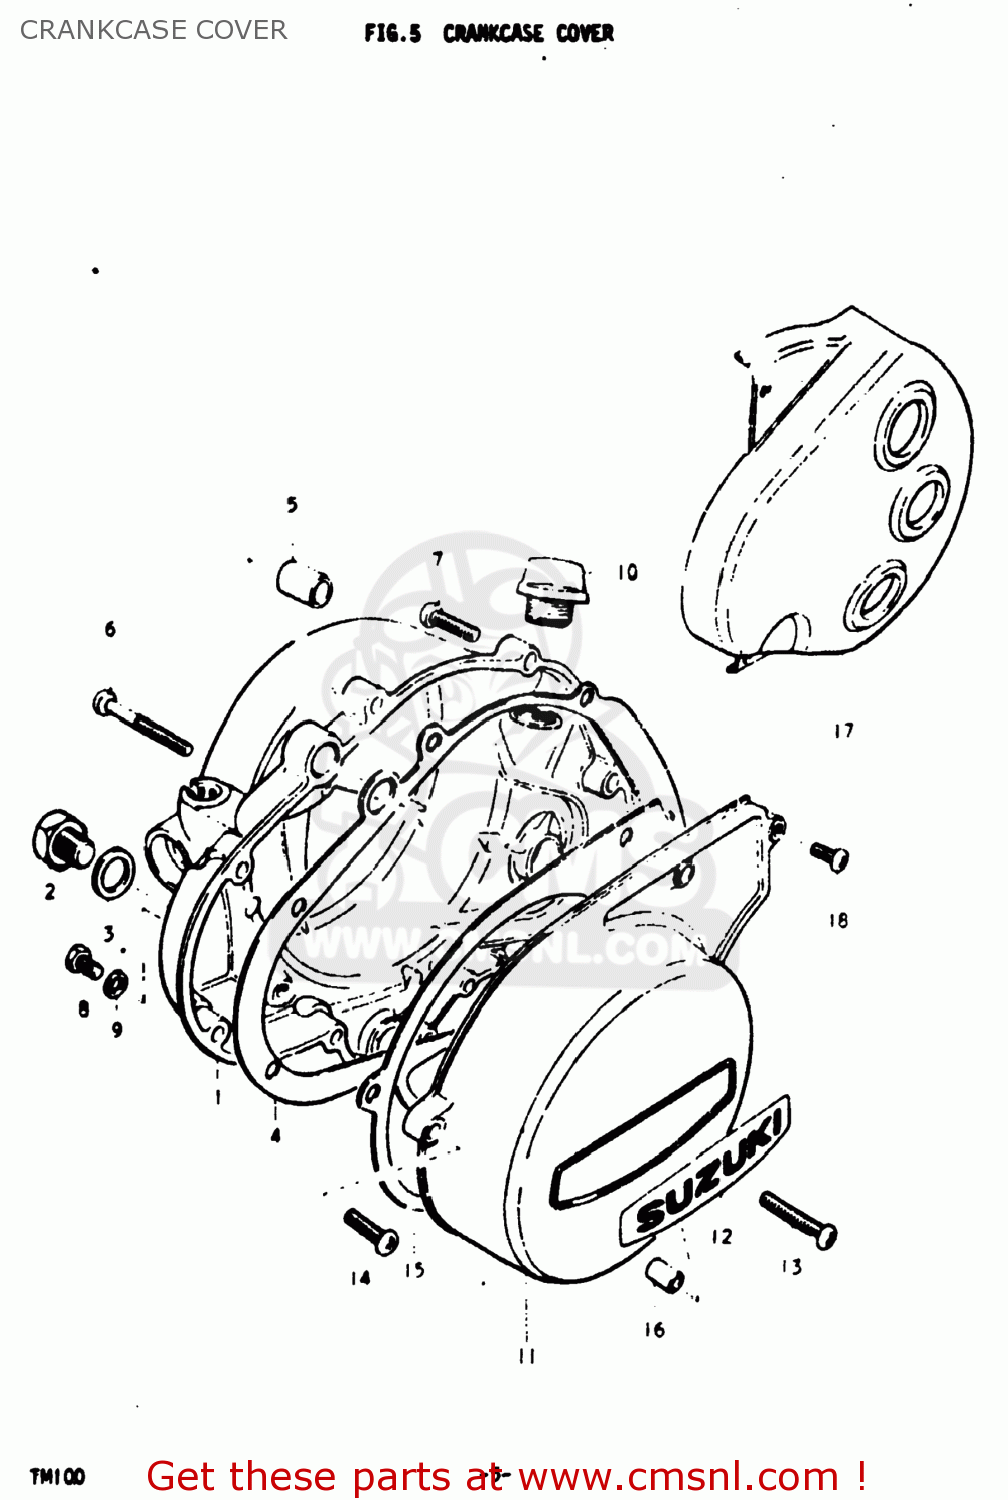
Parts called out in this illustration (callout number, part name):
1	CLUTCH COVER
2	PLUG
3	GASKET(14X19.2X2) (NAS)
4	GASKET,CLUTCH COVER (MCA)
5	PIN
6	SCREW (6X45)
7	SCREW
8	SCREW(6X10)
9	GASKET(6.2X11X1) (NAS)
10	PLUG,OIL FILTER
11	COVER
12	EMBLEM
13	SCREW
14	SCREW
15	GASKET,CLUTCH COVER (NAS)
16	PIN
17	COVER,ENGINE SPROCKET GLOSS
18	SCREW
